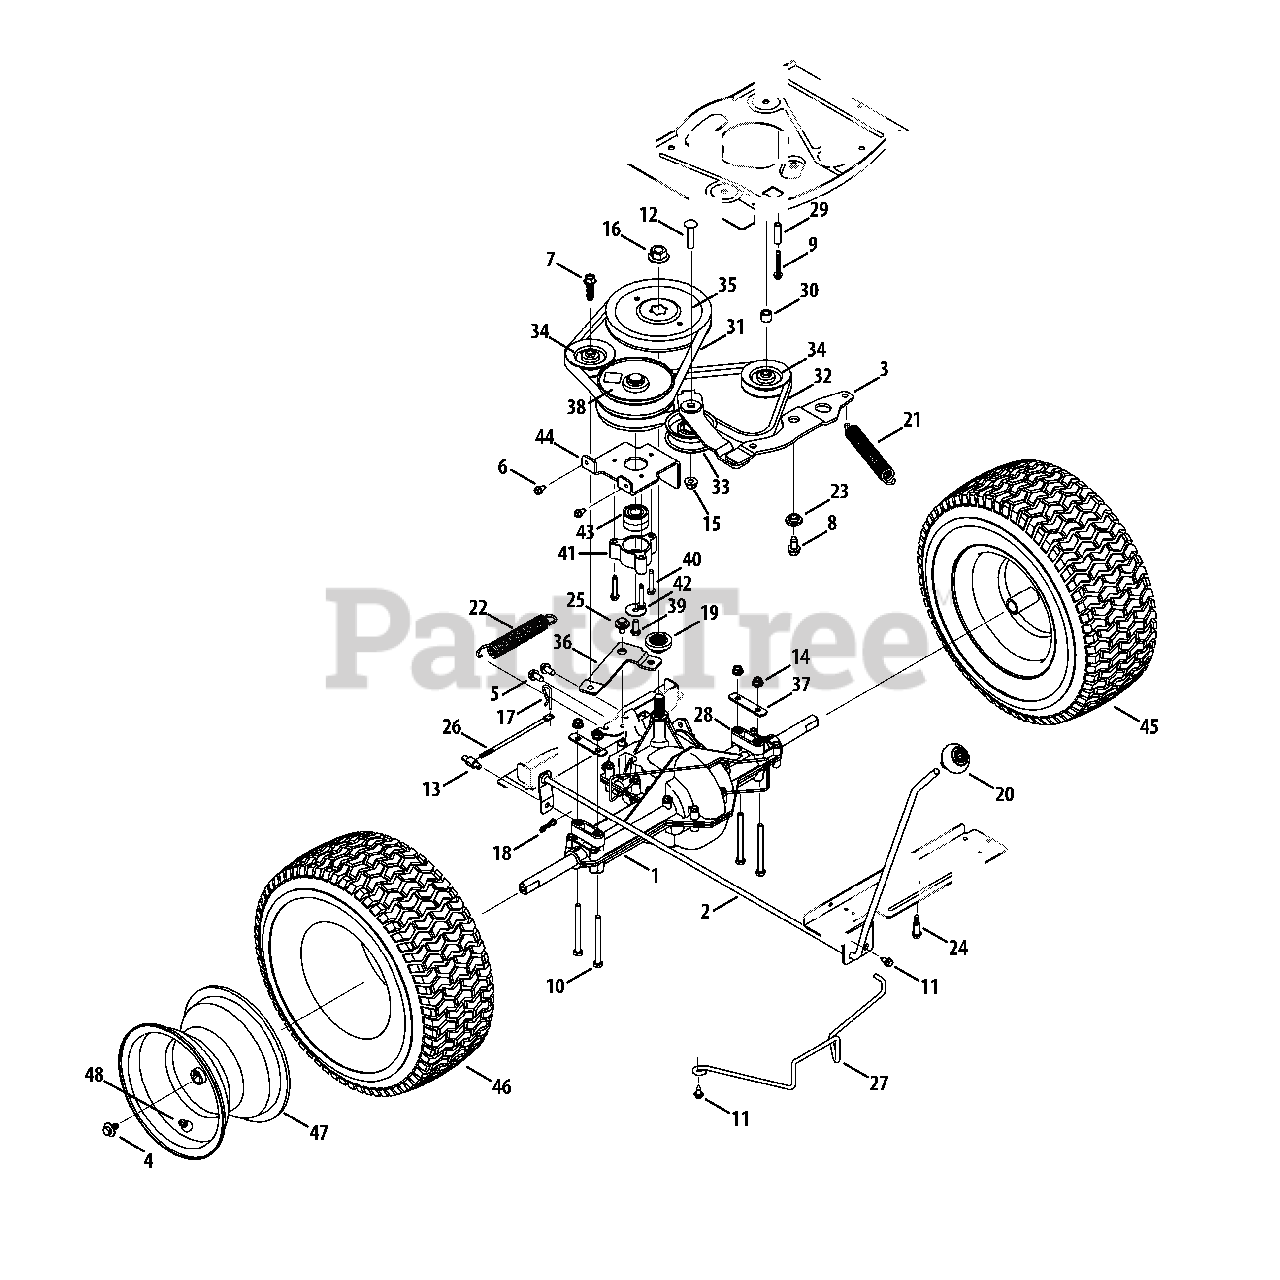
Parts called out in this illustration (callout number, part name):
1	Transmission Assembly
2	Shift Handle Assembly
3	Drive Assembly Idler
4	Screw, 5/16-24 x .750
5	Tap Screw, 5/16-18, .750
6	Tap Scew, 1/4-20, 0.500
7	Screw, 3/8-16 x 1.375
8	Tap Screw, 3/8-16, 0.750
9	Screw, 1/4-20 x 1.750
10	Hex Cap Screw, 5/16-18 x 3.5, Gr5
11	Tap Screw, 1/4-20 x .625
12	Screw, Carriage: 3/8-16 x 1.75"
13	Adjustable Ferrule, 1/4-20 X 1.00
14	Flange Locknut, 5/16-18
15	Flange Lock Nut, 3/8-16
16	Flange Nut, 9/16-18
17	Internal Cotter Pin, .125 Dia.
18	Bow-Tie Cotter Pin
19	Pulley Hub, 5/8 Spline
20	Shift Knob
21	Extension Spring, .94 Dia. X 6.74 Lg.
22	Extension Spring, .97 OD X 6.18
23	Shoulder Spacer, 1.00 X .38 X .38
24	Shoulder Screw, .368 x .75, 1/4-20
25	Shoulder Screw, .560 x .165, 5/16-18
26	Shift Rod
27	Deck Belt Keeper, 30"
28	Spacer
29	Spacer, .260 X .372 X 1.420
30	Spacer, .385 x .625 x .500
31	V-Belt, 5L:35.25
32	V-Belt, 5L:35.28
33	Flat Idler Pulley, 2.75 OD
34	V-Type Idler Pulley, 3.06
35	V-Type Pulley, 6.56
36	Rear Idler Arm Bracket
37	Transaxle Mounting Bracket
38	Variable Speed Pulley Assembly
39	Hex Head Lock Screw, 5/16-24:.750
40	Tap Screw, 1/4-20:1.500
41	Bearing Cup
42	Flat Washer, .330x1.250x.060
43	Ball Bearing, 17 X 40 X 12
45	Complete Wheel Assembly
46	Tire, 16 x 6.5 x 8 Sq. Shldr.
47	Rim Assembly, 8.0 x 5.38
48	Air Valve
